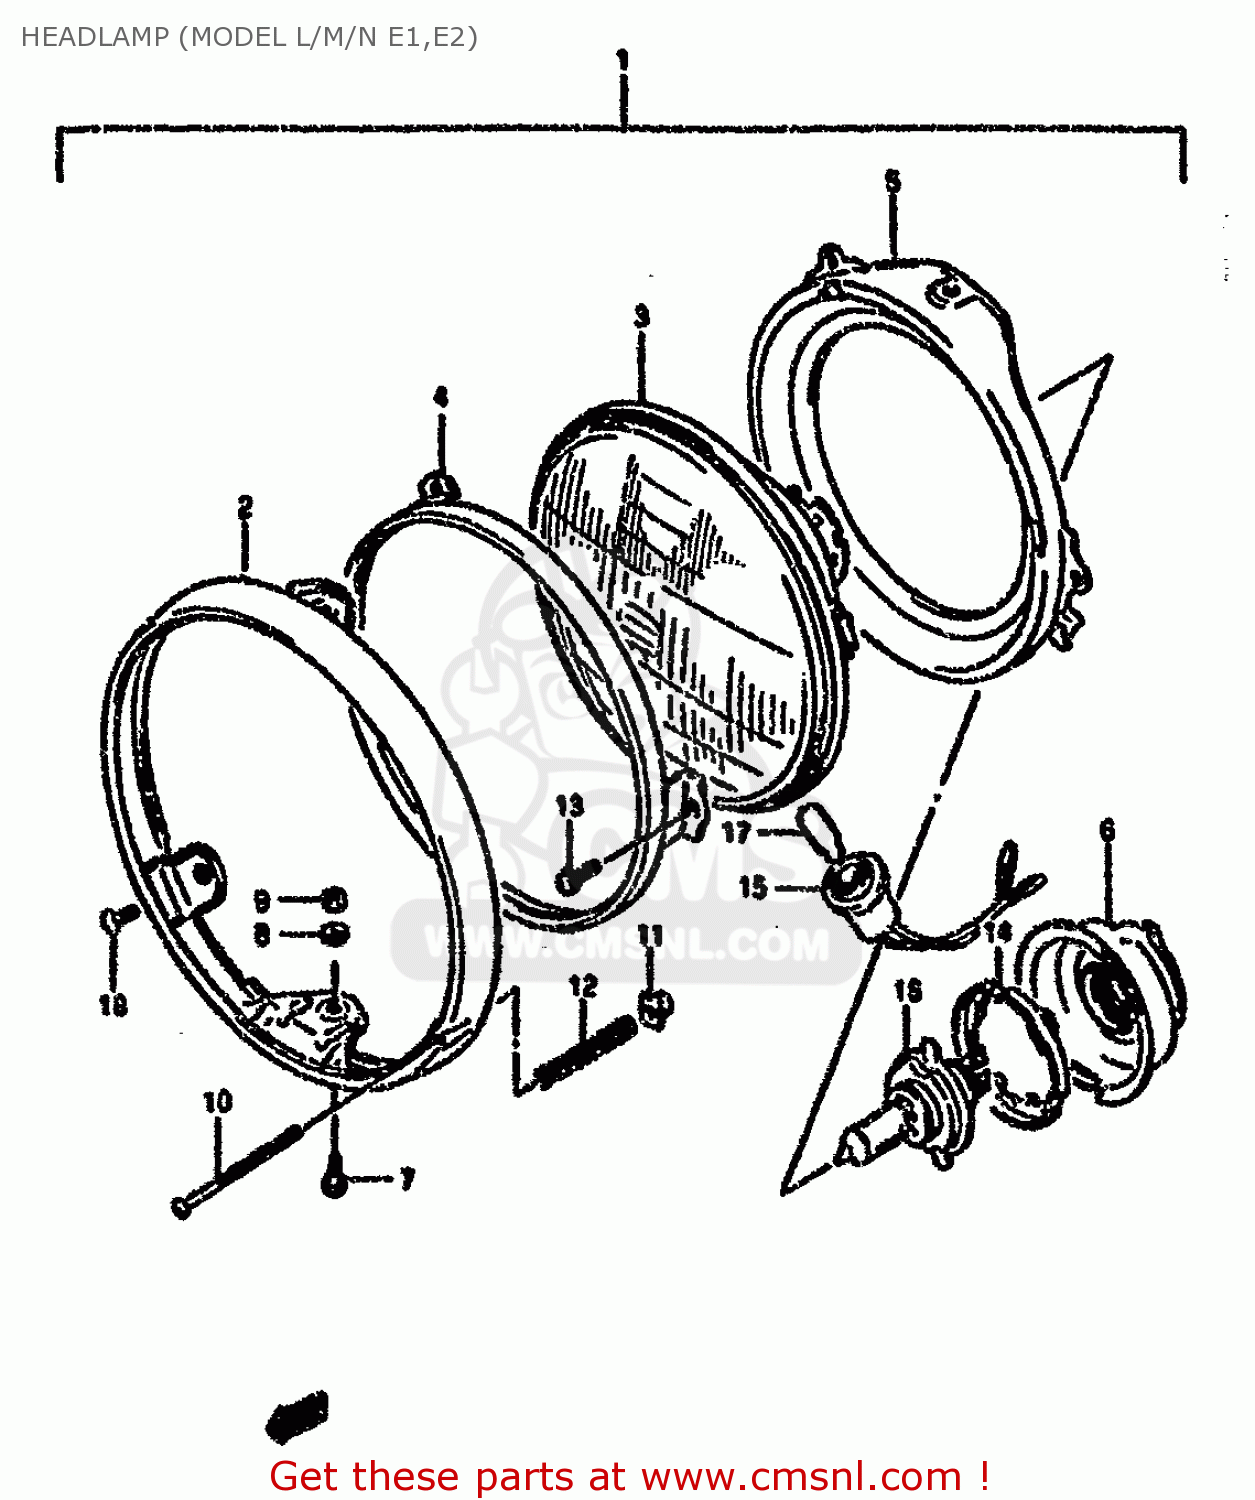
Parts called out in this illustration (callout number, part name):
1	HEADLAMP ASSY
2	RIM,HEADLAMP
3	LAMP UNIT
4	RETAINING RING
5	RING
6	COVER,HEADLAMP SOCKET
7	H/LAMP LENS UNIT FITING SCRE
8	WASHER,LOCK
9	NUT
10	SCREW
11	NUT
12	SPRING,ADJUSTING
13	SCREW
14	SETTING,BULB
15	SOCKET
16	BULB(12V60/55W,H4)
17	BULB(12V4W)
18	SCREW
